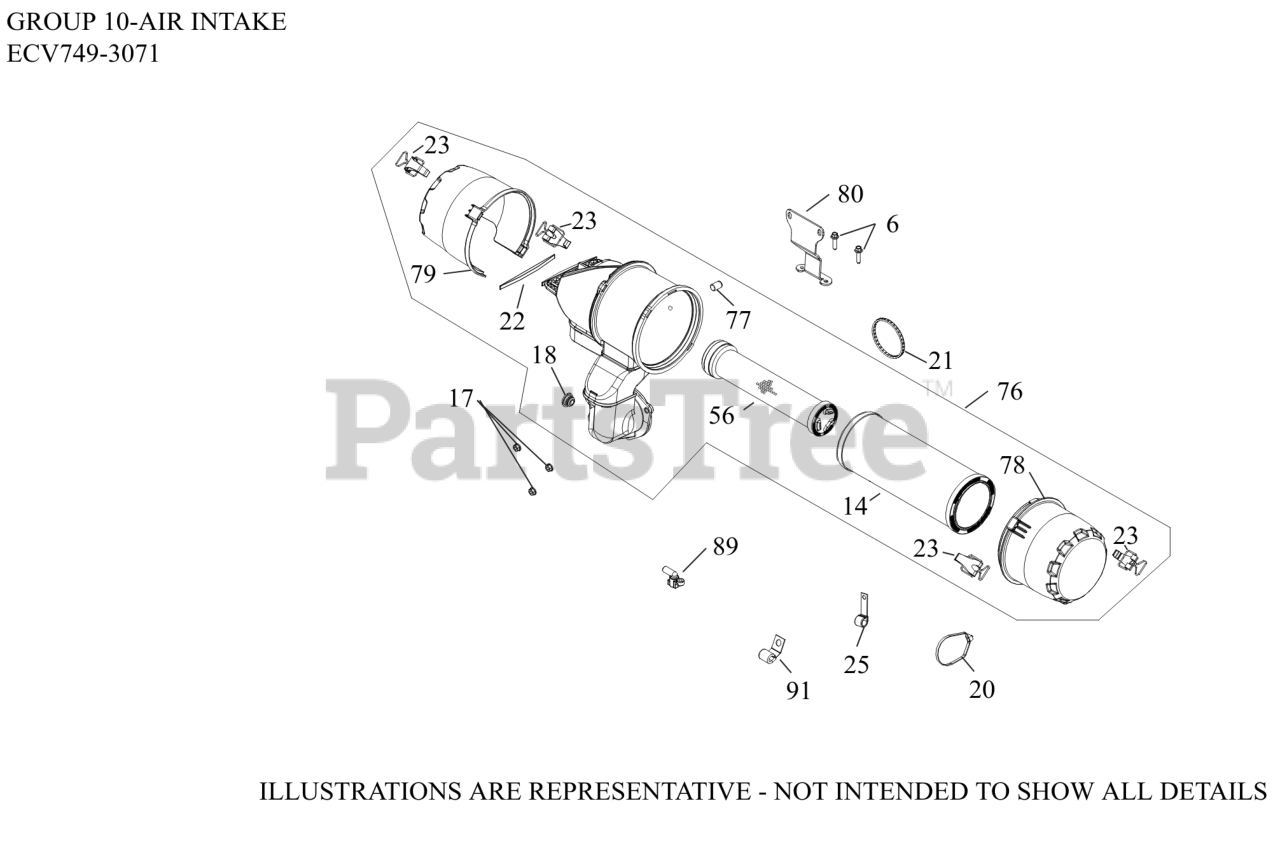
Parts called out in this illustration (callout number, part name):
6	SCREW, FLG M6X1.0X16
14	ELEMENT, AIR FILTER - PRIMARY
17	NUT, FLG M6X1.0
18	PLUG, HOLE
21	O-RING (HDAC SEAL-EFI)
22	DAMPER, FOAM INSERT
23	CLIP ASSEMBLY
25	CLIP, CABLE
56	ELEMENT, AIR FILTER - SAFETY
76	FILTER ASSEMBLY, AIR - OIL FILTER SIDE
77	CAP, MASKING
78	COVER, AIR FILTER
79	COVER, RAIN CAP
80	BRACKET, SUPPORT
89	FITTING, EVAP CONNECTOR
